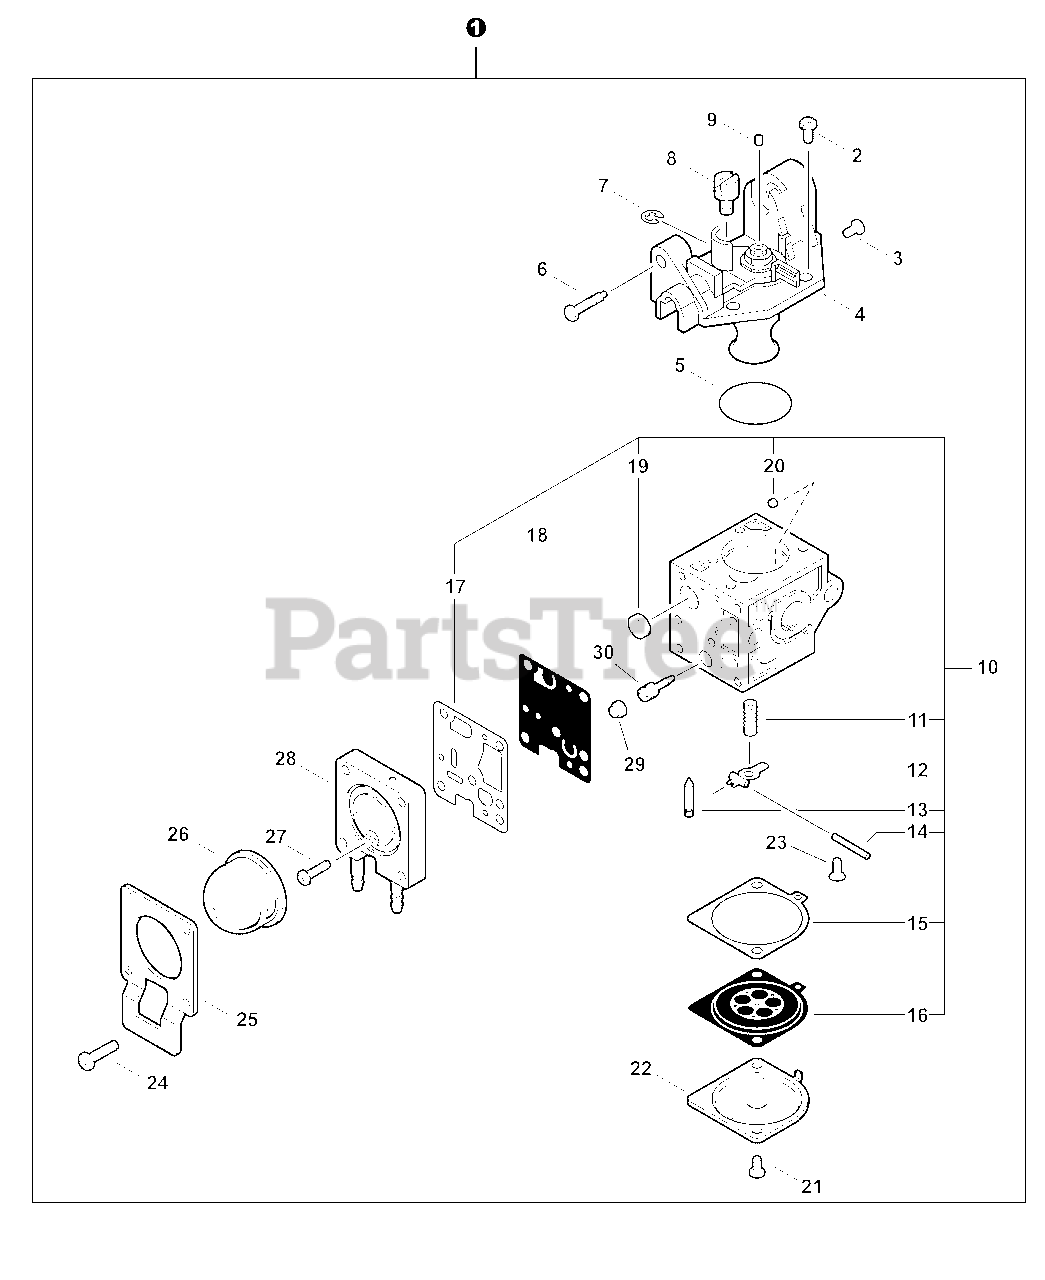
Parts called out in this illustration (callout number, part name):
1	CARBURETOR - RB-K91
4	COVER ASSY, ROTOR
6	SCREW, IDLE ADJUST
10	REPAIR KIT
11	SPRING, METERING LEVER
12	LEVER, METERING
13	VALVE, INLET NEEDLE
14	PIN, METERING LEVER
15	GASKET, DIAPHRAGM
16	DIAPHRAGM, METERING
17	GASKET, PUMP
18	DIAPHRAGM, PUMP
19	STRAINER
20	GUIDE, ROLLER
22	COVER, METERING DIAPHRAGM
25	RETAINER, PURGE BULB
26	BULB, PURGE
28	BODY ASSY, PURGE
30	NEEDLE, HIGH SPEED
